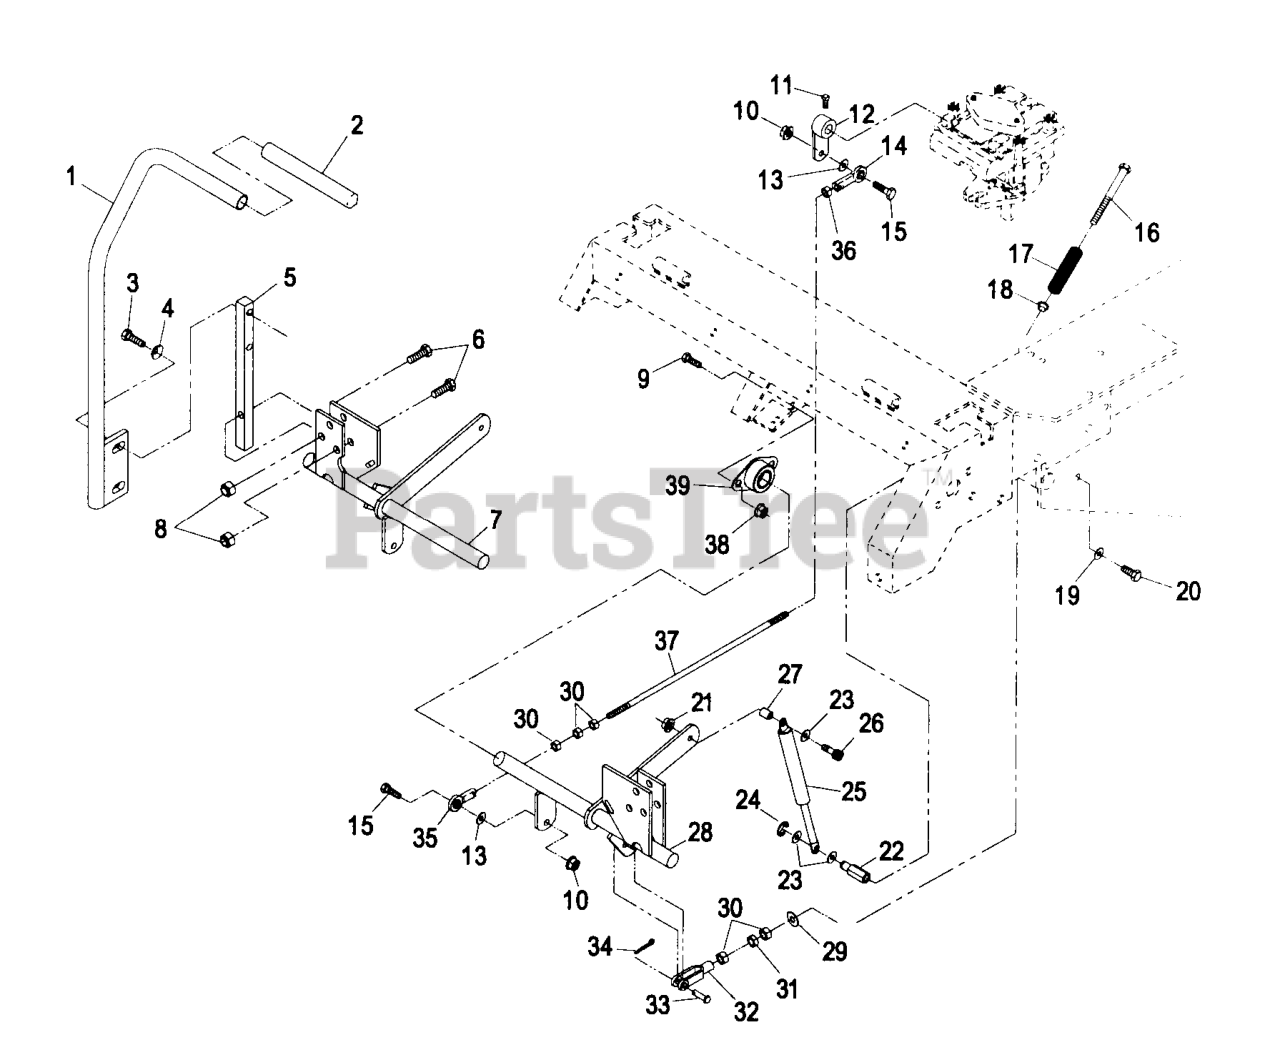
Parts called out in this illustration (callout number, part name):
1	ASM,LEVER/GRIP RH
2	GRIP-CONTROL, MOTION
5	ARM-CONTROL, SHAFT
11	SCREW-SET
14	BALLJOINT-LH
16	BOLT-RETURN, NEUTRAL
17	SPRING-RETURN, NEUTRAL
18	BUSHING-FLANGED
19	WASHER-SPRING
26	SCREW-HSH
32	YOKE-ADJUSTABLE
33	PIN-CLEVIS
35	BALLJOINT-RH
39	BEARING-FLANGE, SIDE
